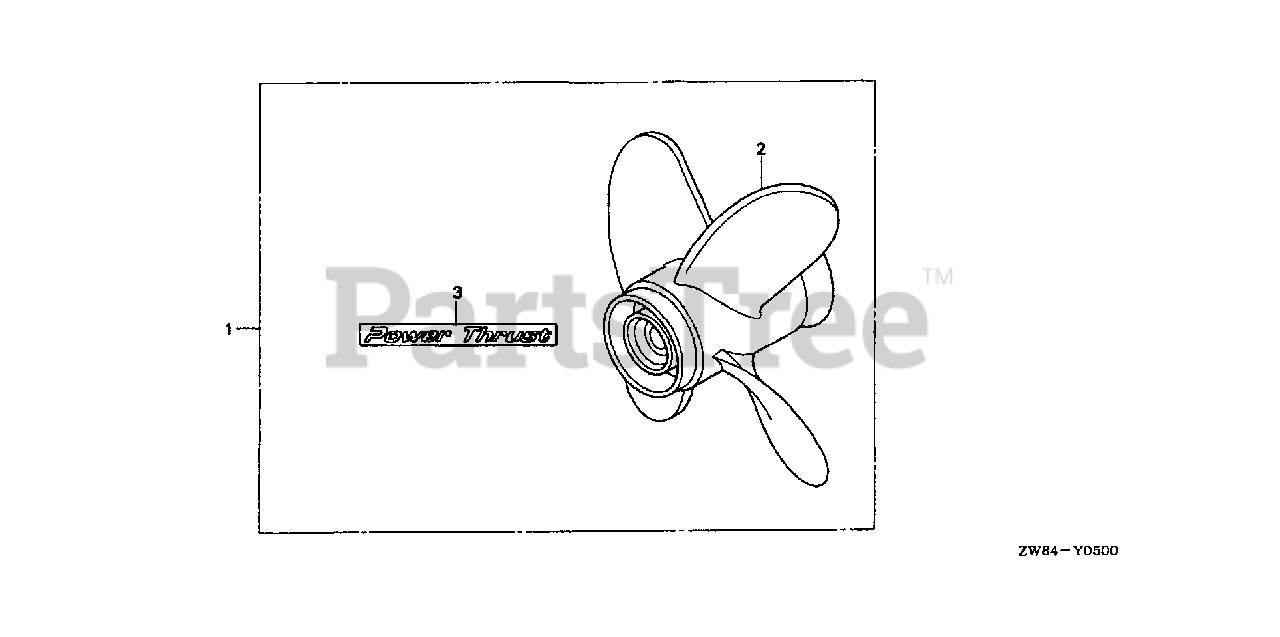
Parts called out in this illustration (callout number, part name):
1	PROPELLER KIT, POWER THRUST
2	PROPELLER, FOUR BLADES
3	MARK, POWER THRUST
